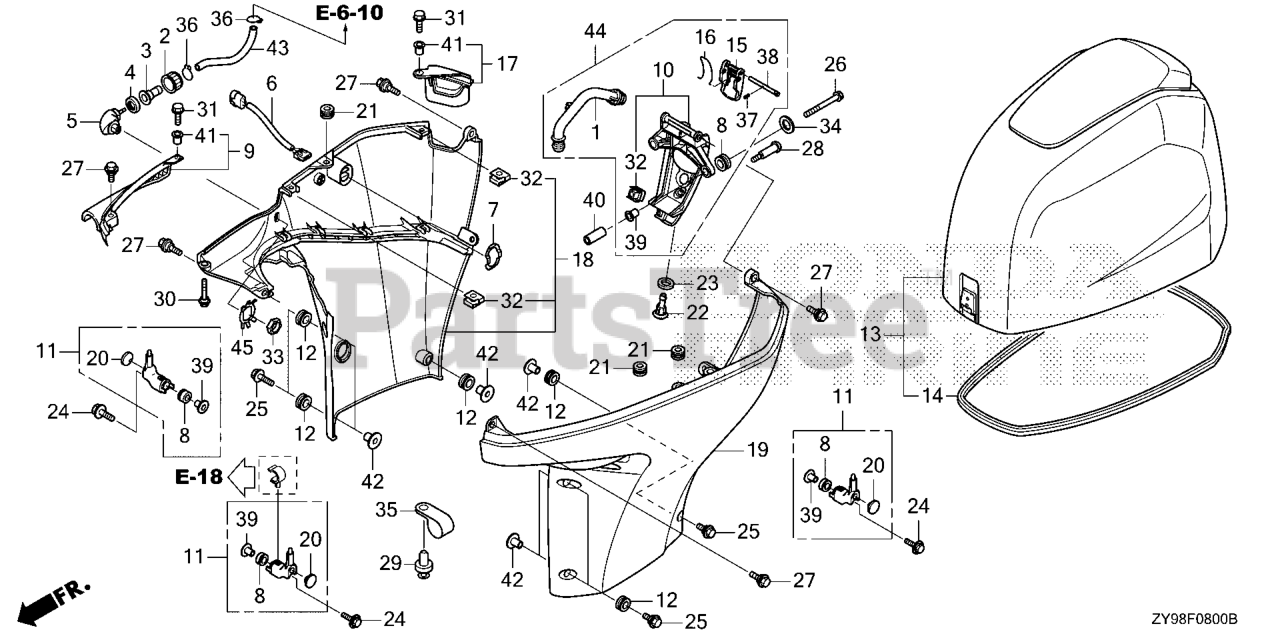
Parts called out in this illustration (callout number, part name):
1	PORT, IDLE EX.
2	NUT, WATER MOUTH
3	JOINT, WATER HOSE
4	SEAT, WATER MOUTH
5	CAP, WATER JOINT
6	SWITCH ASSY., POWER TILT
7	STAY, POWER TILT SWITCH
8	GROMMET, CASE (LOWER)
9	COVER, FR. SEPARATE *NHB14M* (AQUA MARINE SILVER METALLIC)
10	BRACKET, COVER (LOWER)
11	STOPPER ASSY., ENGINE SIDE
11	STOPPERNASSY
12	RUBBER, FENDER MOUNTING
13	COVER, ENGINE *NHB14M* (AQUA MARINE SILVER METALLIC)
14	SEAL, ENGINE COVER
15	LEVER, FASTENER
16	WIRE, FASTENER
17	COVER, PLUG MAINTENANCE *NHB14M* (AQUA MARINE SILVER METALLIC)
18	COVER, R. ENGINE (LOWER) *NHB14M* (AQUA MARINE SILVER METALLIC)
19	COVER, L. ENGINE (LOWER) *NHB14M* (AQUA MARINE SILVER METALLIC)
20	RUBBER, SEAT SIDE
21	GROMMET, ENGINE COVER
22	GROMMET, WATER CHECK
23	SEAL, WATER CHECK GROMMET
24	BOLT-WASHER (6X27) (CT200)
24	BOLT-WASHER (6X27)
25	BOLT-WASHER (6X22)
26	BOLT, FLANGE (6X55)
27	BOLT, SPECIAL (6X17)
28	BOLT, RR. BRACKET
29	SCREW, RIVET (5X10)
30	BOLT, SPECIAL (6X37)
31	BOLT (6X20)
31	BOLT, FLANGE (6X20) (SH)
33	NUT, HEX. (16MM) DUAL QTY = (2) (SINGLE)
34	WASHER, PLAIN (6MM)
35	CLIP (10.7MM)
37	PIN, SPRING (2.0X12)
38	PIN (5X59)
39	COLLAR, MODULE IGNITION CONTROL CASE (CDI)
39	COLR, CDI UNIT CASE
39	COLLAR (12X6.5)
40	COLLAR, DISTANCE (6.5X11X27)
40	COLLAR (6.5X11X27)
41	COLLAR, DISTANCE (6.5X9X11.5)
42	COLLAR, DISTANCE (6.2X7.5)
43	BULK HOSE, FUEL (8X1000) (95001-80001-(95001-80001-60M)
44	BRACKET, RR. COVER
45	WASHER, TONGUED
